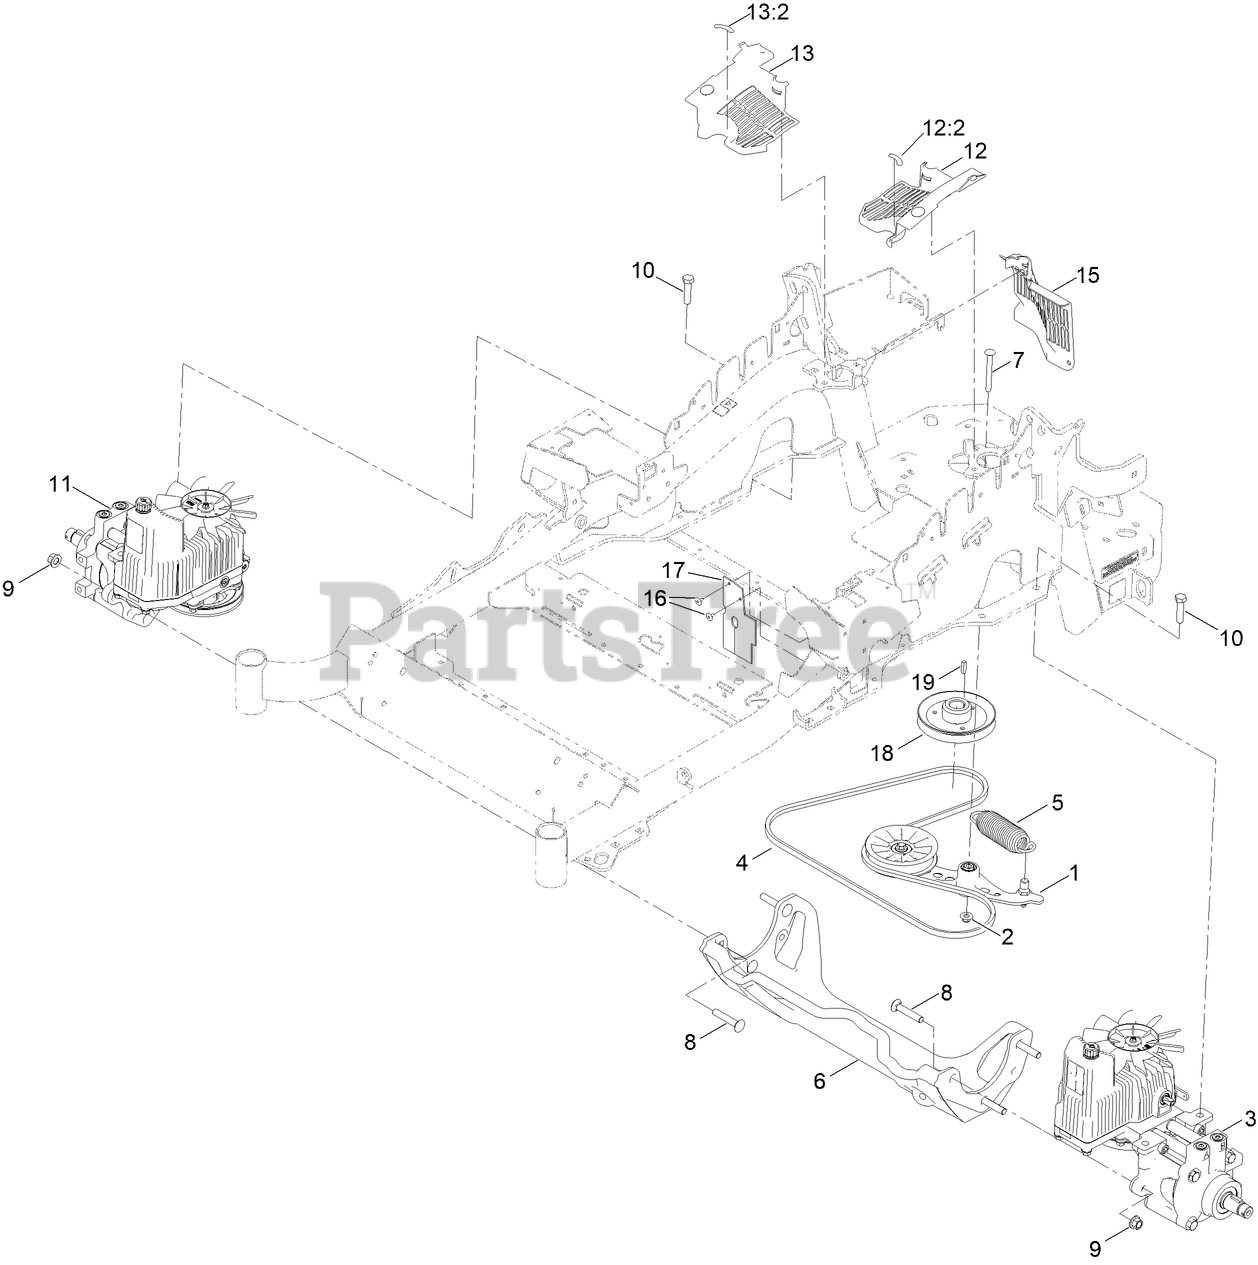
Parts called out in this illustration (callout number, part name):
1	PUMP IDLER ASM
2	NUT-FLANGE, NI
3	HYDRO-LH
4	BELT-V
5	SPRING-EXTENSION
6	CRADLE-HYDRO
7	BOLT-SHOULDER, CARRIAGE
8	SCREW-CARR
9	NUT-LOCK
10	SCREW-HH
11	HYDRO-RH
12	LH HYDRO GUARD ASM
12:2	DECAL-OIL, HYDRO
13	RH HYDRO GUARD ASM
13:2	DECAL-OIL, HYDRO
15	GUARD-HYDRO, REAR (RH)
16	RIVET-POP
17	DEFLECTOR-AIR FLOW
18	SHEAVE, W/HUB
